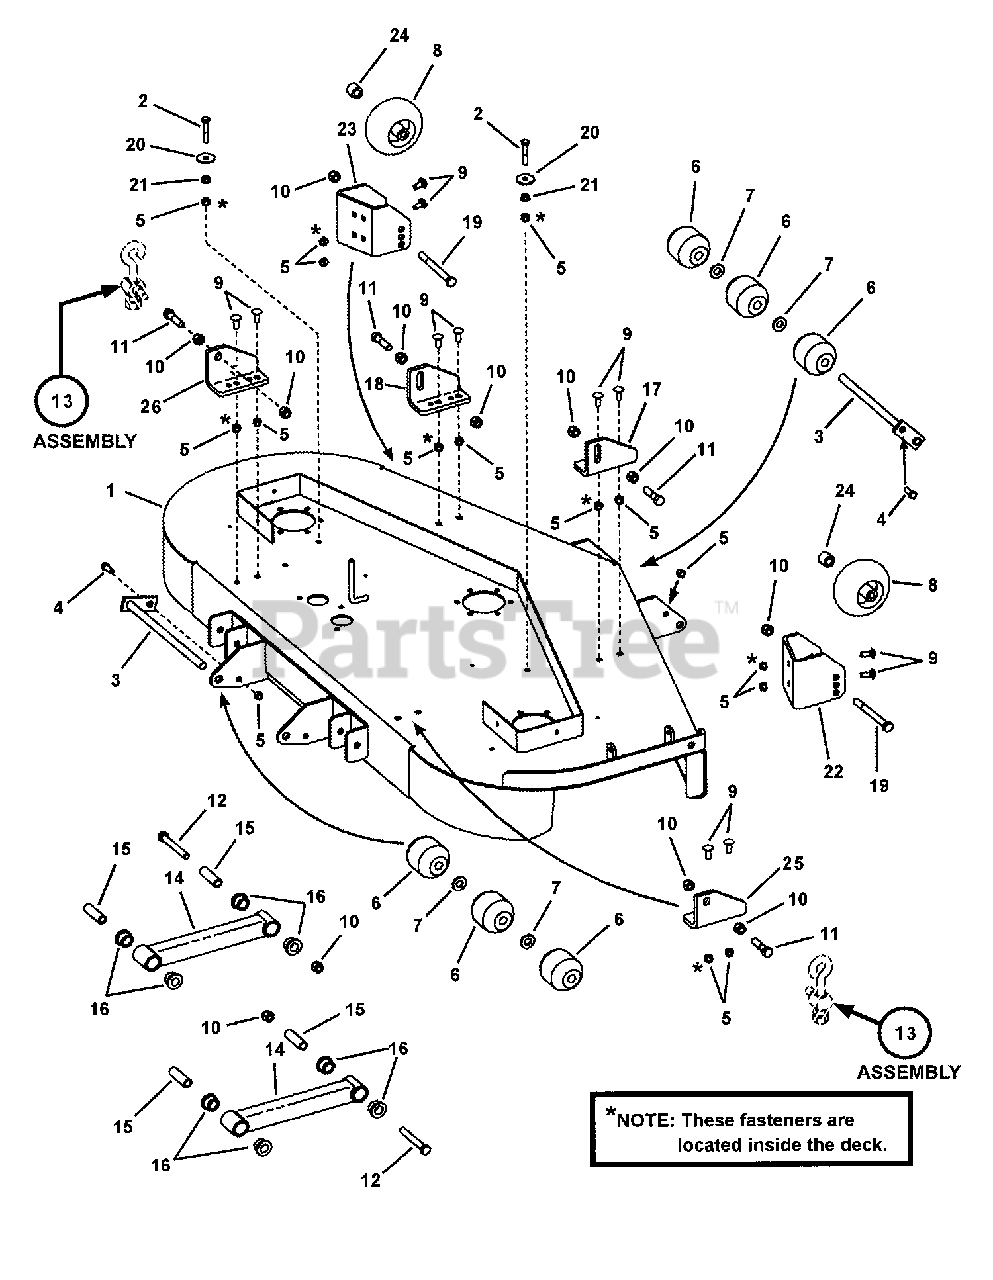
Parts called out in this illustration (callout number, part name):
1	WELDMENT, 61" Deck
2	SCREW, 3/8-16 x 2" Hex Head Cap, GR 5
3	WELDMENT Pivot Pin
4	SCREW, 3/8-16 x 1" Hex Head Cap, GR 5
5	NUT, 3/8-16 Hex Nyloc
6	ROLLER, Low Density Polyethylene
7	WASHER, 5/8" Flat SAE
8	GAUGE WHEEL, Polyethylene
9	BOLT, 3/8-16 x 1" Square Neck Carriage, GR 5
10	NUT, 1/2-13 Hex Light Nyloc
11	SCREW, 1/2-13 x 2" Hex Head Cap, GR 5
12	BOLT, 1/2-13 x 3-3/4" Hex Head Cap, GR 5
14	WELDMENT, Pusher Bar
15	SLEEVE - Suspension
16	BUSHING - Suspension
17	BRACKET, Deck Lift, Right Hand
18	BRACKET, Deck Lift, Left Hand
19	BOLT, 1/2-13 x 5" Hex Head
20	WASHER, .406 x 1.50 x .120 Flat
21	NUT, 3/8-16 Hex Flange Lock
22	WHEEL BRACKET, Front Right
23	WHEEL BRACKET, Front Left
24	SPACER, Gauge Wheel
25	BRACKET, Deck Lift, RH Rear
26	BRACKET, Deck Lift, LH Rear
